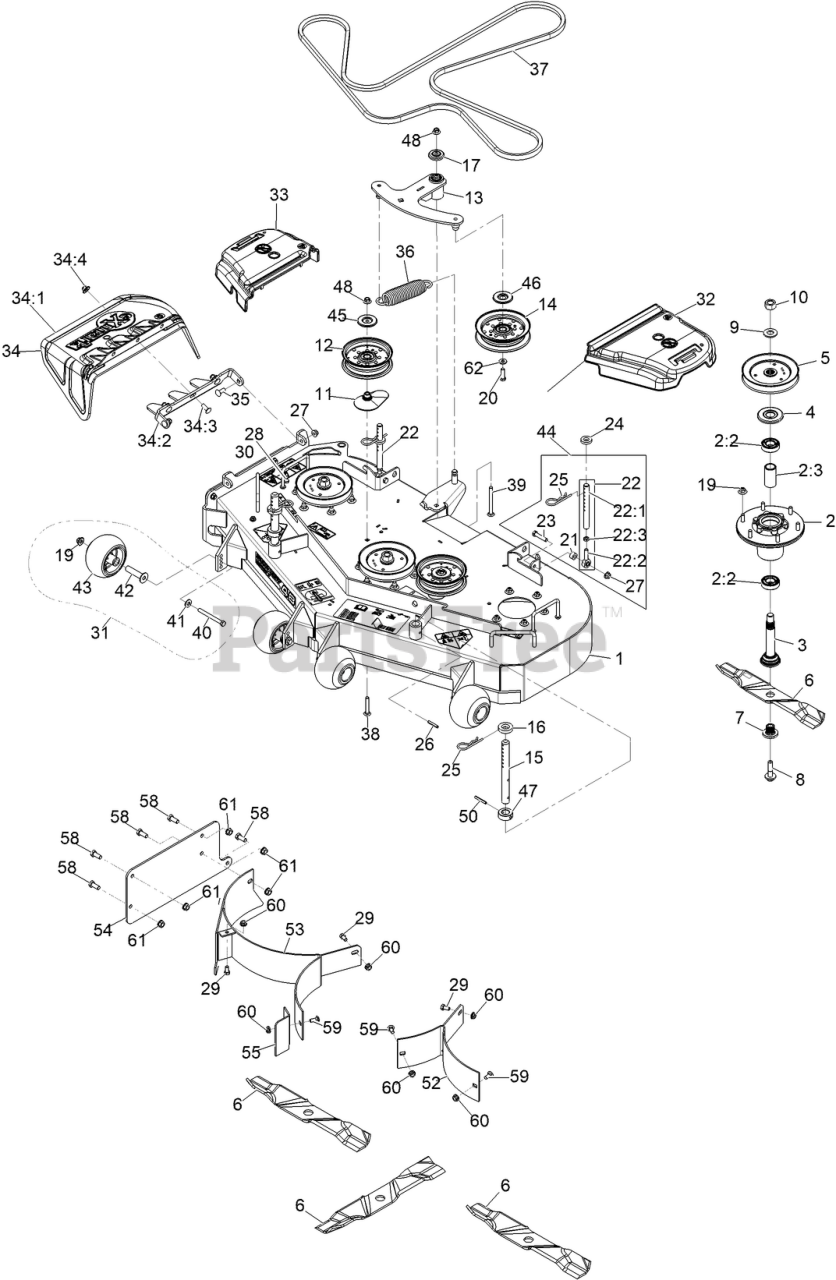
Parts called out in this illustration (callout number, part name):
1	ASM, DECK 48" W/DECALS
2	ASM-CUTTER HSG WITH BEARINGS
2:2	BEARING-BALL
2:3	SPACER-BEARING
3	ASM-SPINDLE AND SEAL
4	GUARD,BEARING TOP .989
5	SHEAVE,BLADE DRIVE 5.90
7	BUSHING,SPLINED
8	SCREW,SEMS 1/2-20 X 2.19
10	NUT-HEX
11	SPACER-PULLEY
12	IDLER-PULLEY, FLAT 5.00X1
13	ASM, DECK IDLER
14	IDLER-PULLEY, FLAT
15	ROD, DECK SUPPORT TTS
16	SPACER-DECK SUPPORT
17	GUARD-TOP
19	Nut-Nyloc 3/8-16 Flg
20	SCREW-HH
22:1	LINK,SUPPORT
22:2	BALLJOINT
22:3	NUT-HJ
23	SCREW-HH
25	PIN,HAIR COTTER
27	NUT-HF, NI
28	SCREW-HH
29	SCREW-HH
30	NUT-HF, NI
31	KIT, ANTI-SCALP ROLLER
32	COVER-BELT, LH
33	COVER-BELT, RH
34	ASM, DISCHARGE CHUTE
34:1	CHUTE,DISCHARGE
34:2	BRACKET, DISCHARGE CHUTE
34:3	SCREW-CARR
34:4	Nut-Nyloc 3/8-16 Flg
35	SCREW-CARR
36	SPRING-EXTENSION
38	BOLT-CARR, SHORT NECK
39	SCREW-CARR
40	SCREW-HH 3/8-16 X 3 3/4 GR 8
41	WASHER-BELLEVILLE
42	AXLE, ROLLER
43	ROLLER-SCALP, ANTI
44	KIT,SUPPORT LINK W/PIN
45	SHIELD-DUST
46	SHIELD-GUARD, DUST
47	COLLAR, DECK HEIGHT PIN
50	PIN-ROLL
53	BAFFLE-RH
54	PLATE, MULCH COVER
55	BAFFLE-BLOCKER
58	SCREW-HH
59	BOLT-CARR
61	NUT-HHF, WHIZ
